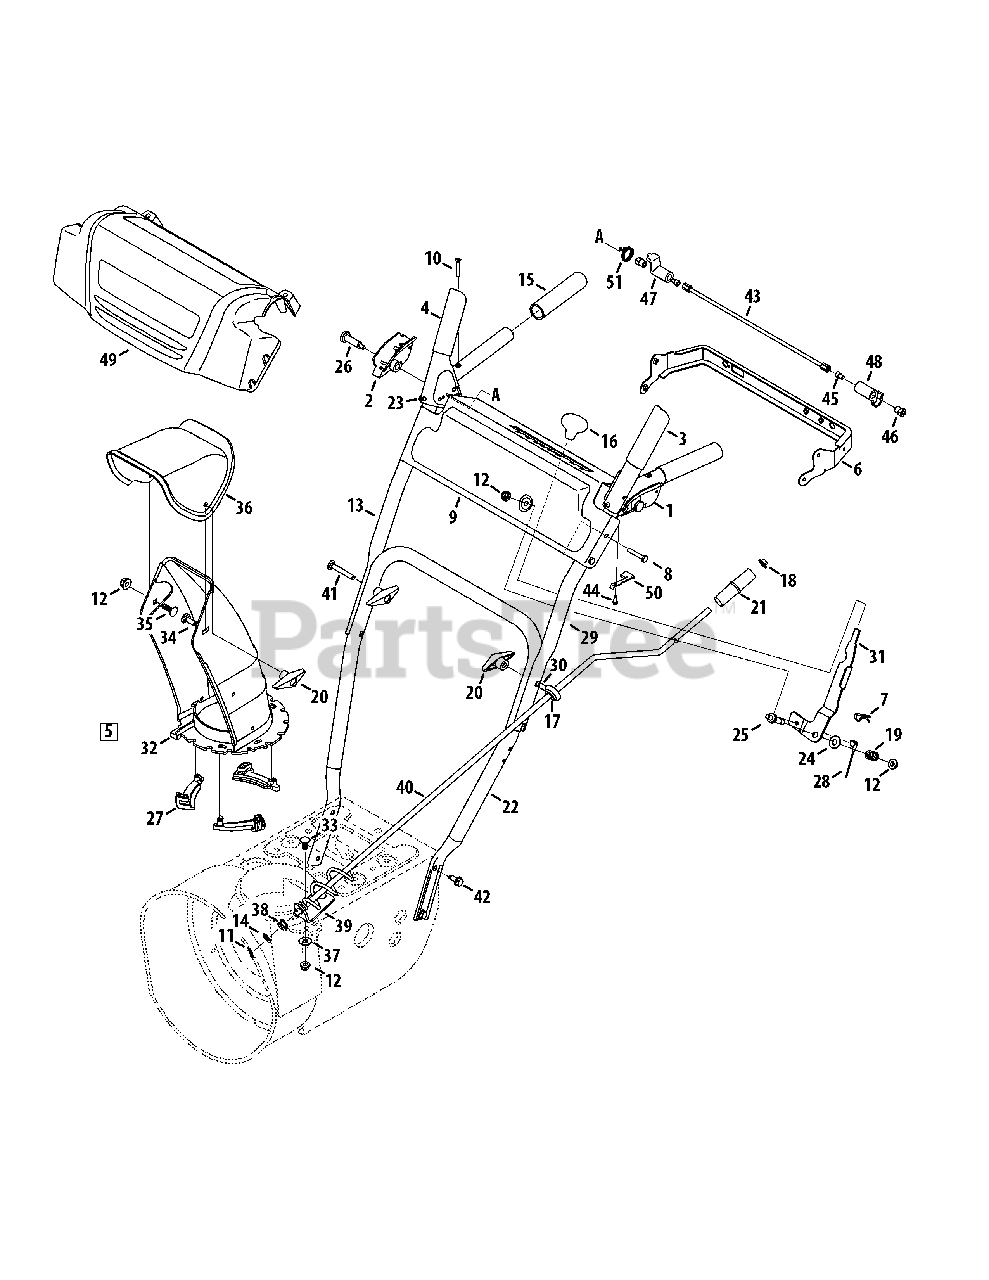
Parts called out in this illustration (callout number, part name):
1	Handle Assembly, Clutch Lock, LH
2	Handle Assembly, Clutch Lock, RH
3	Handle Ass’y, Engage, LH
4	Handle Ass’y, Engage, RH
5	Chute, Lwr (Incl. Ref. # 27, Qty. 3)
6	Bracket, Panel
7	Click Pin
8	Screw, 1/4-20 x 1.625
9	Panel, Handle, (no cutout)
10	Screw, Machine, #10-24, 1.375
11	Pin, Cotter, .072 x 1.13
12	Nut, Flange Lock, 5/16-18, Nylon
13	Handle, Upper, RH
14	Washer, Flat, .375 x .738 x .063
15	Grip, 1.0 ID x 5.0
16	Knob, Shift, Black
17	Grommet, .44 ID x .94 OD x .50
18	Cap, Push, 3/8 Rod
19	Spring, .39 x .60 x .88
20	Knob, 5/16-18, Black
21	Crank Knob, 1.0 Dia. x 3.2, Black
22	Handle, Lower
23	Bumper, Rubber, .62 OD x .22
24	Washer, Flat, .385 x .870 x .092
25	Bolt, Shoulder, 5/16-18 x 0.905
26	Screw, Shoulder, .43 x 1.3, 1/4-20
27	Chute, Flange Keeper
28	Cable, Speed Selector
29	Handle, Upper, LH
30	Eye Bolt, Chute Crank
31	Shift Lever
32	Chute, Lower, 5.0 Dia.
33	Bolt, Carriage, 5/16-18, 1.0
34	Bolt, Carriage, 5/16-18, 1.0
35	Bolt, Carriage, 5/16-18, .750
36	Chute, Upper, w/ Label
37	Washer, .349 x .879 x .063
38	Bushing, Plastic, .380
39	Bracket, Chute Crank
40	Crank Assembly, Chute
41	Screw, Carriage, 5/16-18, 2.25
42	Screw, 5/16-18, 2.25, Gr5
43	Rod, Pivot
44	Screw, #8-16 x .50
45	Screw, 1/4-20 x .50
46	Nut, Hex, 1/4-20
47	Plate, Lock
48	Cam, Clutch Lock
49	Handle Panel Cover
50	Spring, Clutch Lock
51	Spring, Torsion, .8156 ID x .3038
